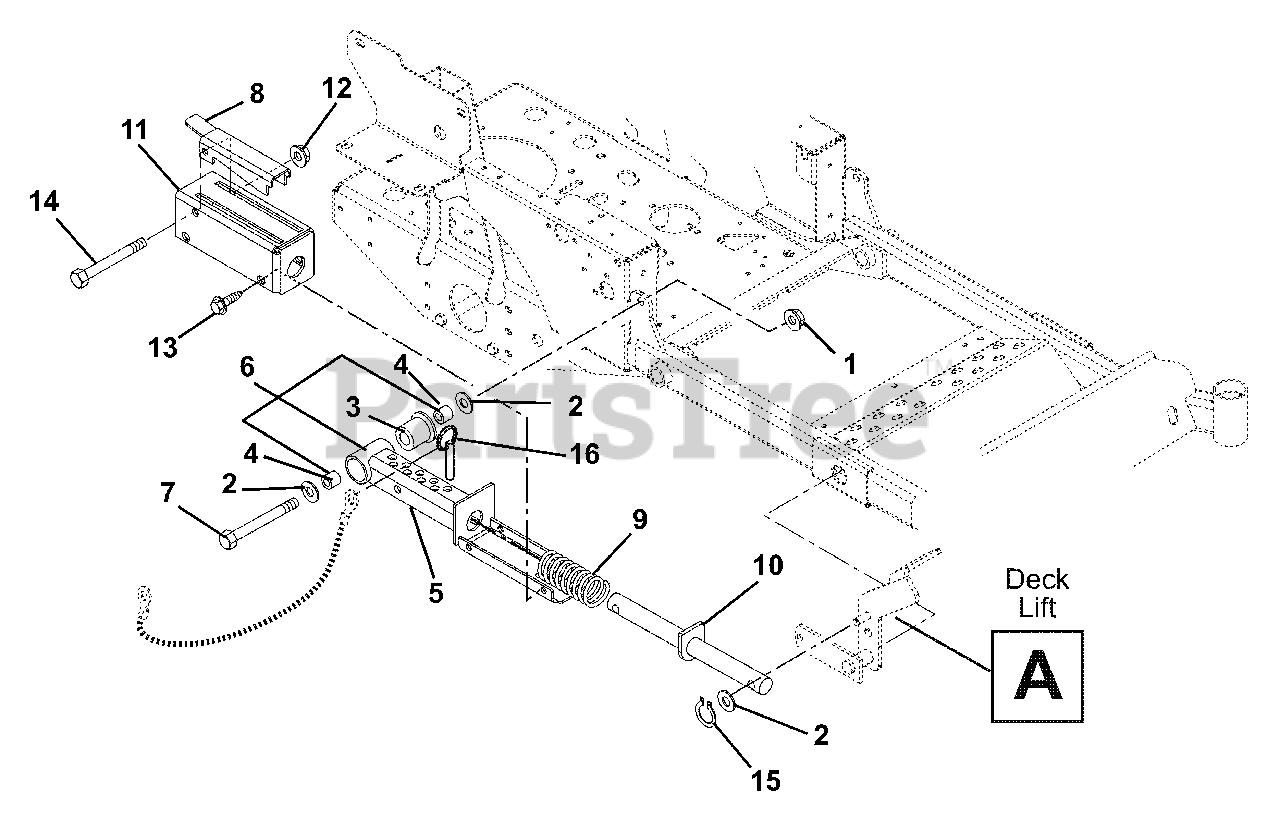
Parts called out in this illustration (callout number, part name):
1	Nut, Locking Top Flange .50-13
2	Washer, Flat Steel .531 x 1.25 x .10
3	Bearing, Pedestal Powdered Metal
4	Bearing, 1.00 x 1.12 x .75
5	Weldment, Mechanical Lift
6	Assembly, Mechanical Lift
7	Bolt, Hex .50-13 x 3.75 Grade 5
8	Lock-Up, Mechanical Lift
9	Spring, Compression 1.13 x 1.48 x 5.10
9	Spring, Compression 1.13 x 1.47 x 5.10
10	Weldment, Mechanical Lift Shaft
11	Weldment, Mechanical Lift Cover
12	Nut, Locking Top Flange .38-16
13	Screw, Tapping .38-16 x .50 Hex Washer Head
14	Bolt, Hex .38-16 x 3.25 Grade 5
15	Ring, Retaining External .50 x .05
16	Pin, Spring Ball .375 O.D. x 1.50
